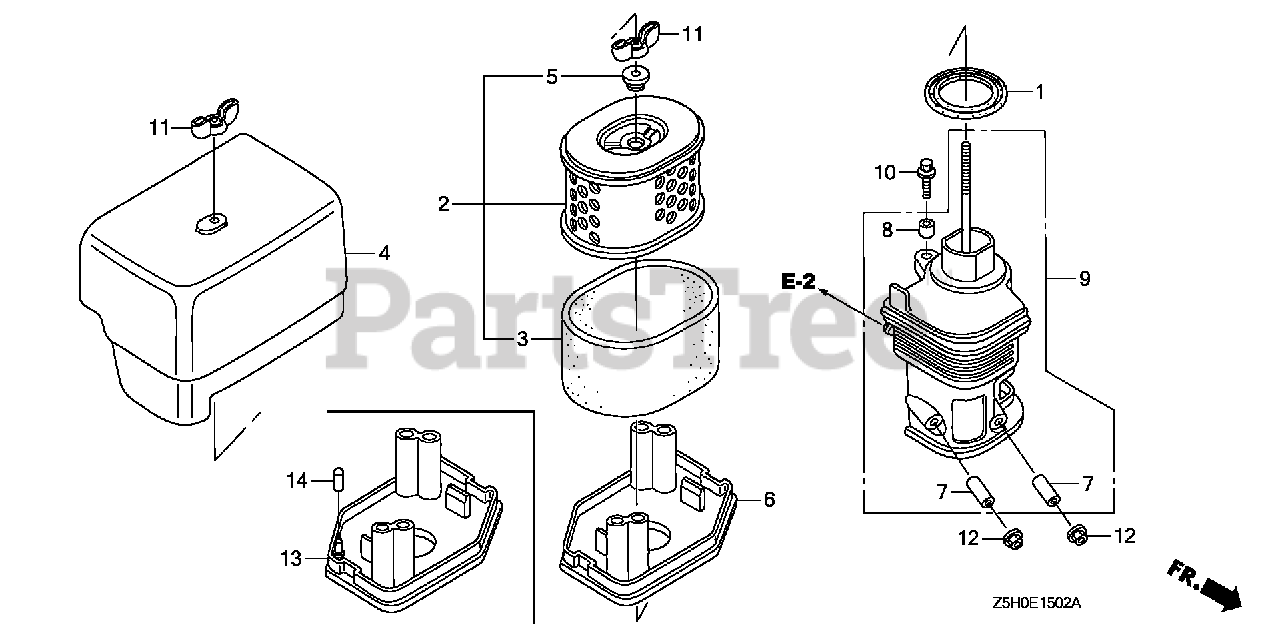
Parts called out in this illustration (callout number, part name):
1	GASKET, ELBOW
2	ELEMENT, AIR CLEANER
3	FILTER (OUTER)
4	COVER, AIR CLEANER (100DB)
5	GROMMET, AIR CLEANER
6	NOSE, MUFFLER
7	COLLAR, AIR CLEANER
8	COLLAR B, AIR CLEANER
9	ELBOW, AIR CLEANER
10	BOLT-WASHER (6X22)
11	NUT, TOOL BOX SETTING
12	NUT, FLANGE (6MM)
